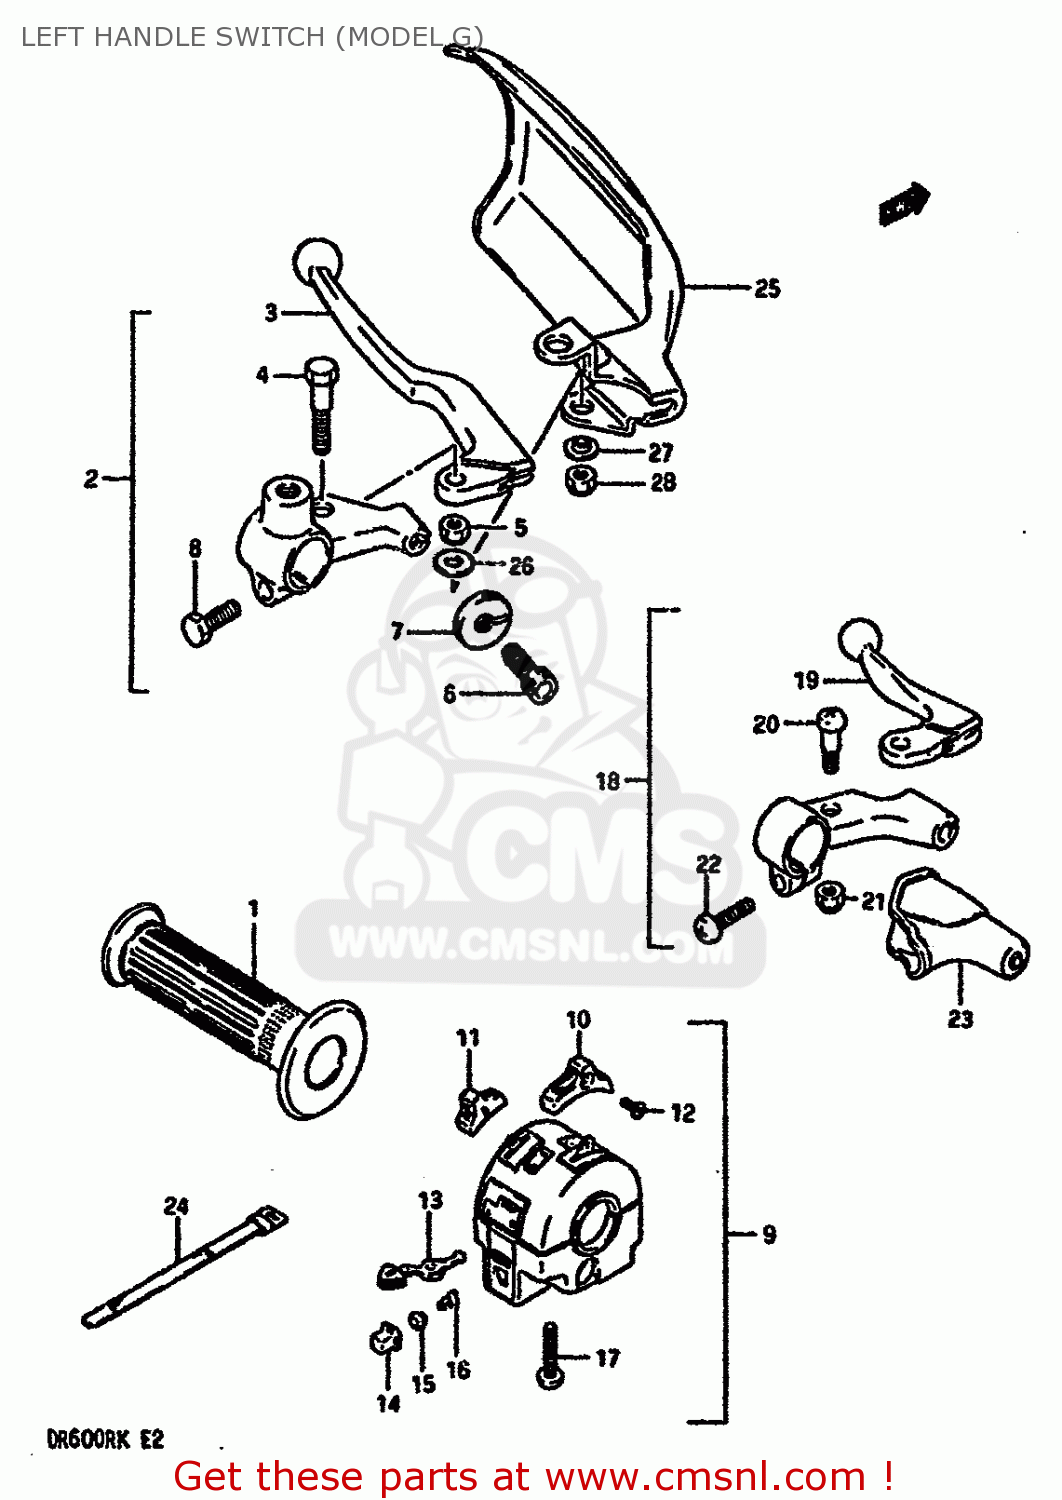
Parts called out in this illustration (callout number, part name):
1	GRIP,L
2	LEVER ASSY,CLUTCH
3	LEVER,CLUTCH
4	BOLT,LEVER PIVOT
5	NUT
6	ADJUSTER,CABLE
7	NUT,CABLE ADJUSTER LOCK
8	BOLT
9	SWITCH ASSY,HANDLE,LH
10	KNOB,LIGHTING SWITCH
11	KNOB,DIMMER SWITCH
12	SCREW
13	KNOB,TURNSIGNAL
14	BUTTON,HORN
15	CONTACT
16	SPRING
17	SCREW
18	LEVER ASSEMBLY,DECOMPRESSION
19	LEVER,DECOMP
20	BOLT,LEVER
21	NUT
22	SCREW
23	COVER,DECOMP LEVER DUST
24	CLAMP(L:120)
25	COVER,KNUCKLE,L
26	WASHER(6.5X16X1.2)
27	WASHER
28	NUT 6MM
